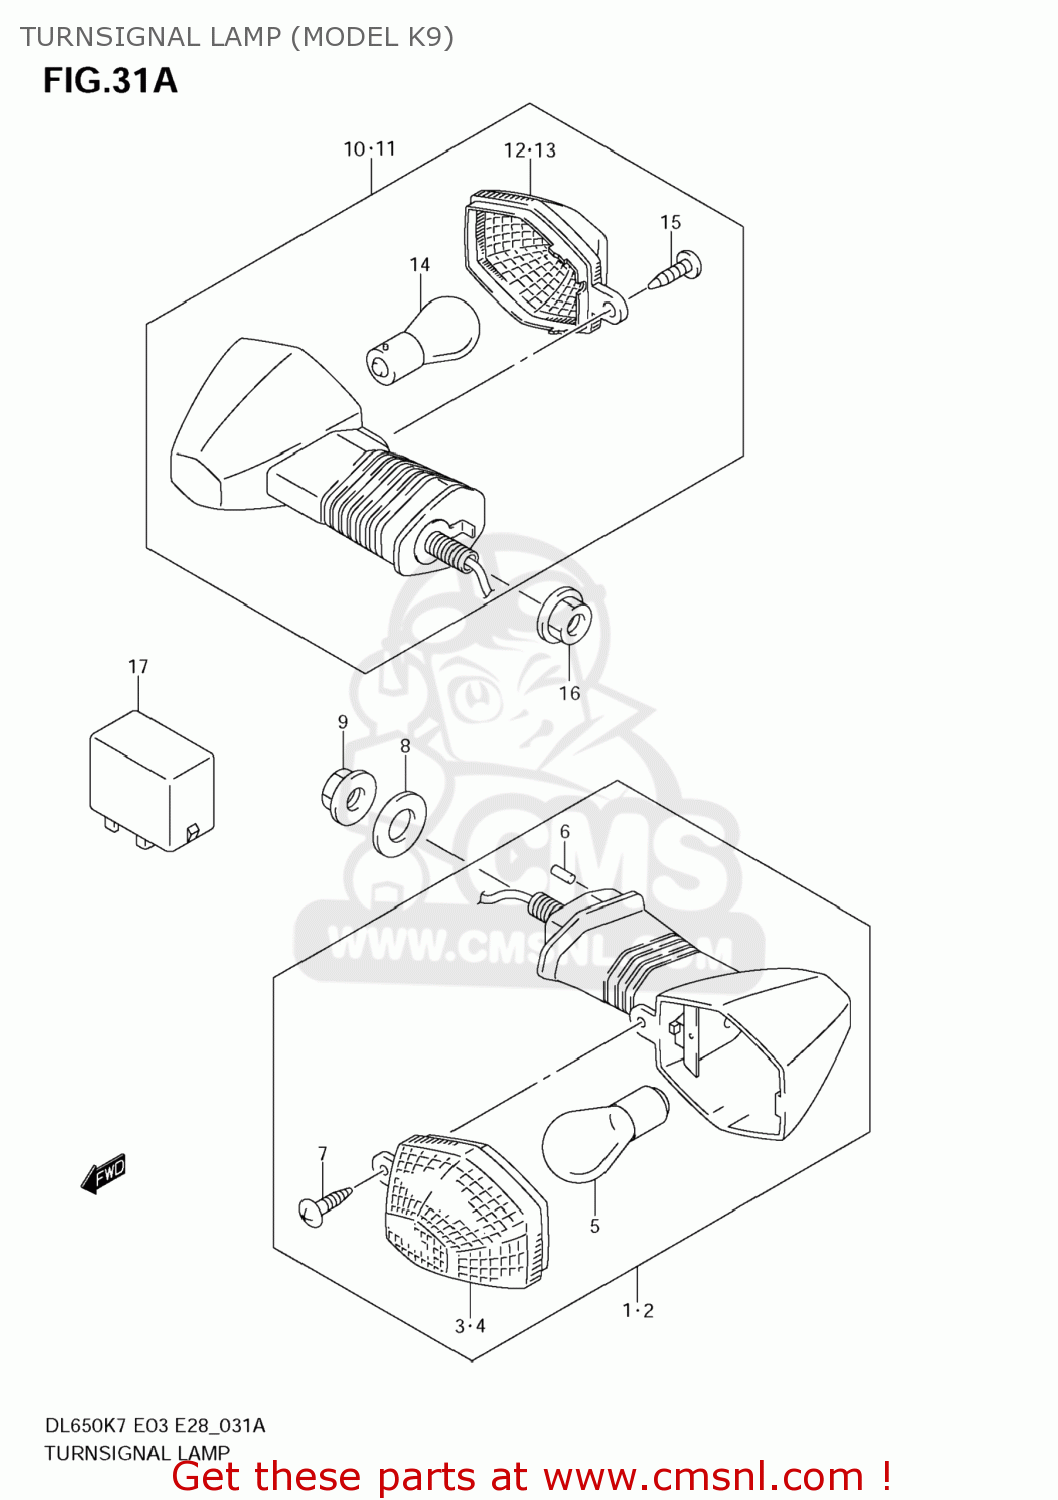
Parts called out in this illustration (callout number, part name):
1	LAMP ASSY,FR TURN SIGNAL,R
2	LAMP ASSY,FR TURN SIGNAL,L
3	LENS
4	LENS
5	BULB(12V21W,AMBER)
6	PIN(4.5X9.5)
7	SCREW
8	WASHER(12.5X30X1.6)
9	NUT
10	LAMP ASSY,RR TURNSIGNAL,R
11	LAMP ASSY,RR TURNSIGNAL,L
12	LENS
13	LENS
14	BULB(12V21W,AMBER)
15	SCREW
16	NUT
17	RELAY ASSY,TURNSIGNAL LAMP
